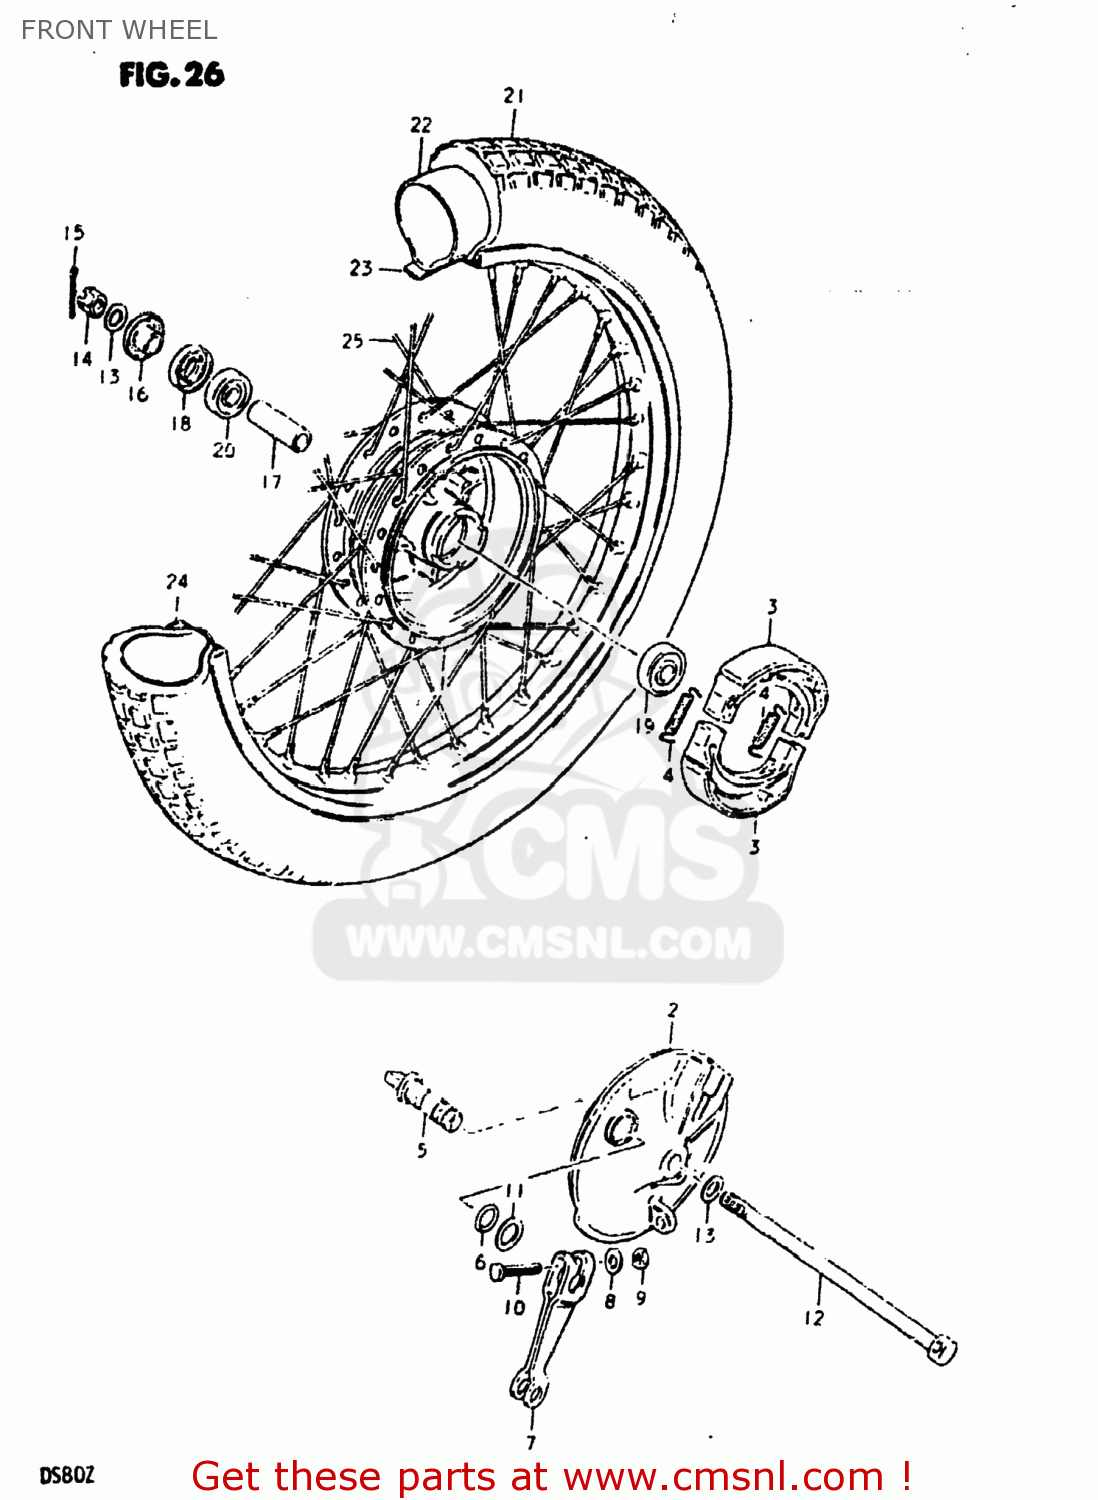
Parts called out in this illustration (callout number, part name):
1	HUB,FRONT
2	PANEL,FR BRAKE ANCHOR
3	SHOE,BRAKE (MCA)
4	SPRING(L:34)
5	CAM,FRONT BRAKE
6	O-RING (D:2.4 ID:13.8)
7	LEVER,FR BRAKE CAM
8	WASHER
9	NUT
10	BOLT(6X33)
11	WASHER (14.5X22X1.6)
12	AXLE,FRONT
13	WASHER(10.5X22X2.3)
14	NUT
15	PIN 20X20
16	SPACER,FRONT AXLE,RIGHT
17	SPACER (10.2X16X51)
18	SEAL,OIL(15X31X5)
19	BEARING
20	BEARING
21	TIRE(2.25 14)
22	TUBE,INNER
23	PROTECTOR,INNER TUBE
24	RIM,FRONT WHEEL (1.40X14)
25	SPOKE SET,FRONT
